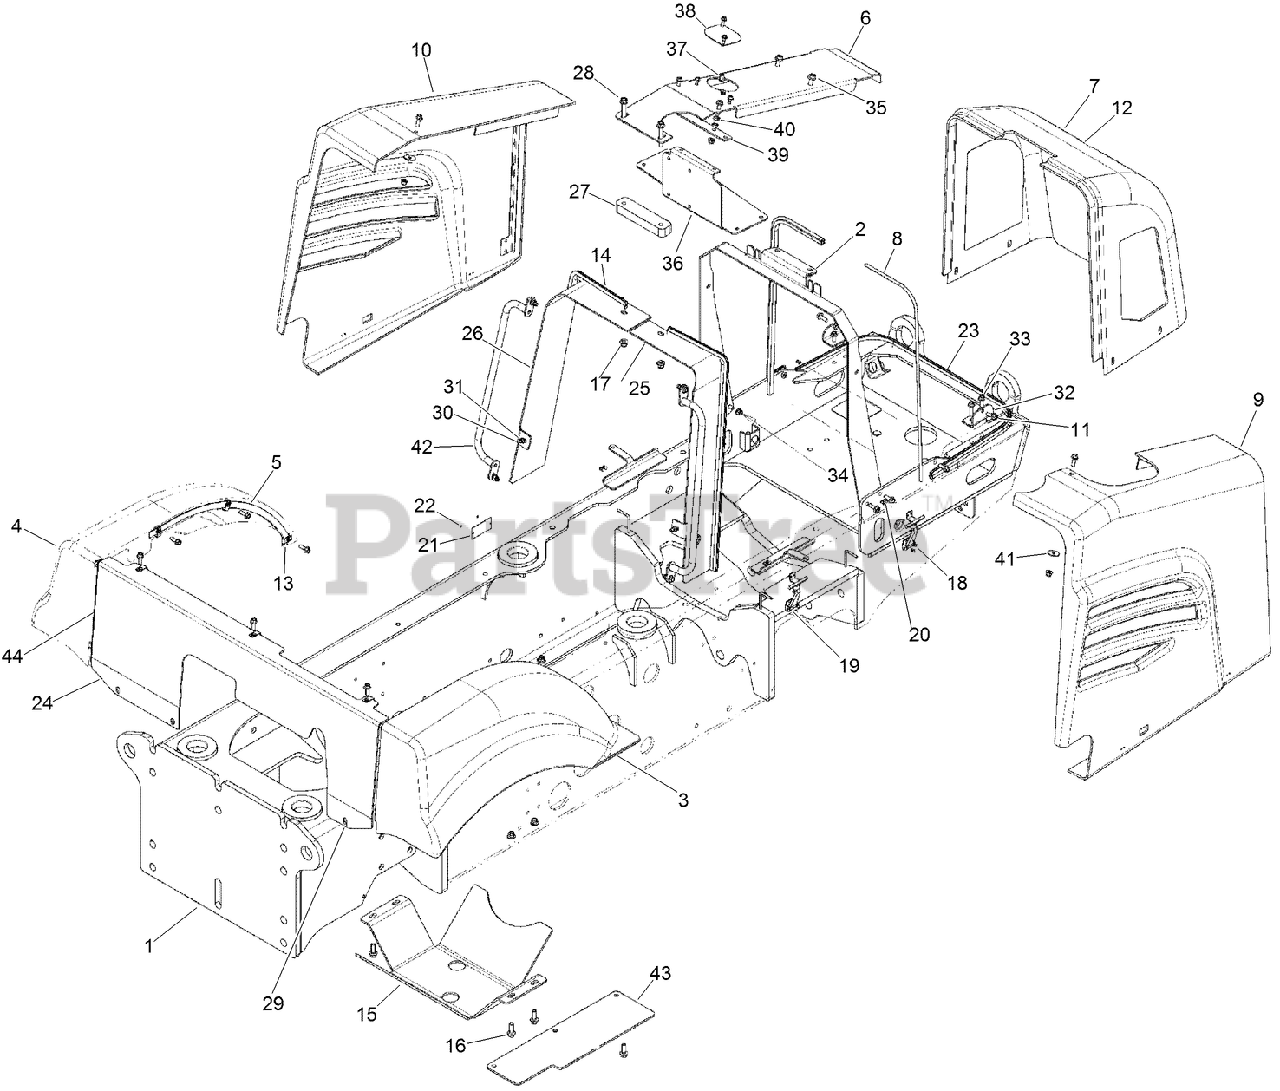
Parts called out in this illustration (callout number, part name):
1	FRAME - Weldment, Chassis
2	PLATE - Upright
3	FENDER-RH
4	FENDER-LH
5	SHEET - Fender Support
6	PLATE - Hood Support
7	CLIP - Nose
8	SEAL - Hood, Front
9	COVER - Engine, RH, RT1200
10	COVER - Engine, LH, RT1200
11	SCREW-HH
12	MEDALLION - Astec Logo
14	SEAL - Hood
15	PLATE - Skid
16	SCREW-HFH
17	NUT-HHF, LOCK
18	LATCH-DRAW, FLEXIBLE
19	RIVET - Blind Brk Mdrl .187 x .450 in ZND
20	RIVET - Blind Brk Mdrl .187 x .700 in ZND
21	PLATE - Serial Number
22	TACK-FASTENER, STEEL
23	SEAL-BOTTOM, NOSE
24	PLATE - Rear Cover
25	PLATE - Console
26	PLATE - Console
27	PLATE - Spacer
28	SCREW-HHF
29	SCREW, METRIC FLANGE w/BODY-M12 x 30
30	SCREW, METRIC FLANGE FULL - M8 x 25
31	NUT-TORQUE, PREVAILING
32	WELDMENT - Support
33	SCREW-HHF
34	NUT-FLANGE, NYLOCK
36	PLATE - Radiator Support
38	COVER - Radiator
39	PLATE - Hood Support
41	WASHER - .406 x 1.50 x .119 in CST ZND
42	WELDMENT - Handle
43	ASSEMBLY - Skid Plate
44	PLATE - Fender Reinforcement
